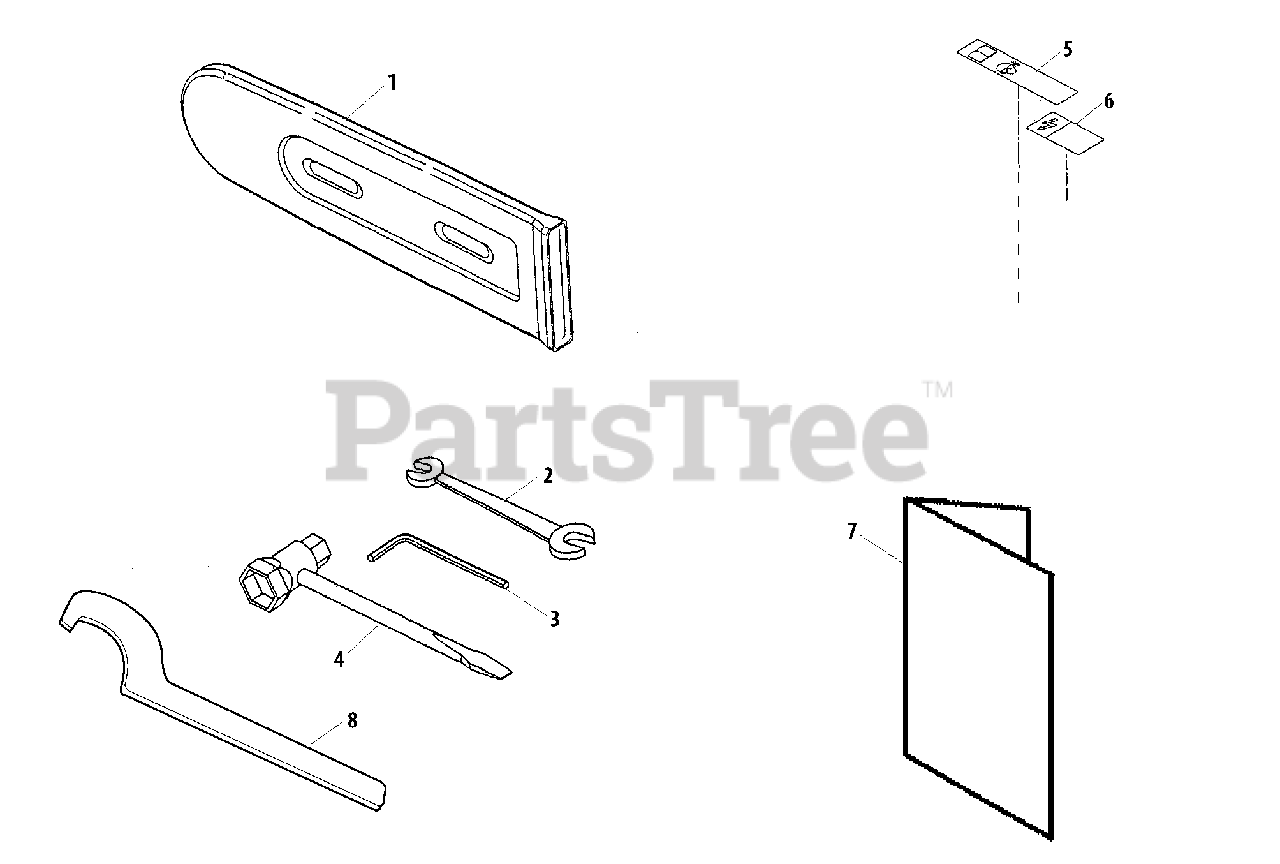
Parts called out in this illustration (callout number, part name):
1	SCABBARD
2	SPANNER 8×10
3	WRENCH, ALLEN 4 MM
4	T-WRENCH
5	LABEL, CAUTION
6	LABEL - CAUTION
7	OWNER'S MANUAL
8	HOOK, SPANNER
